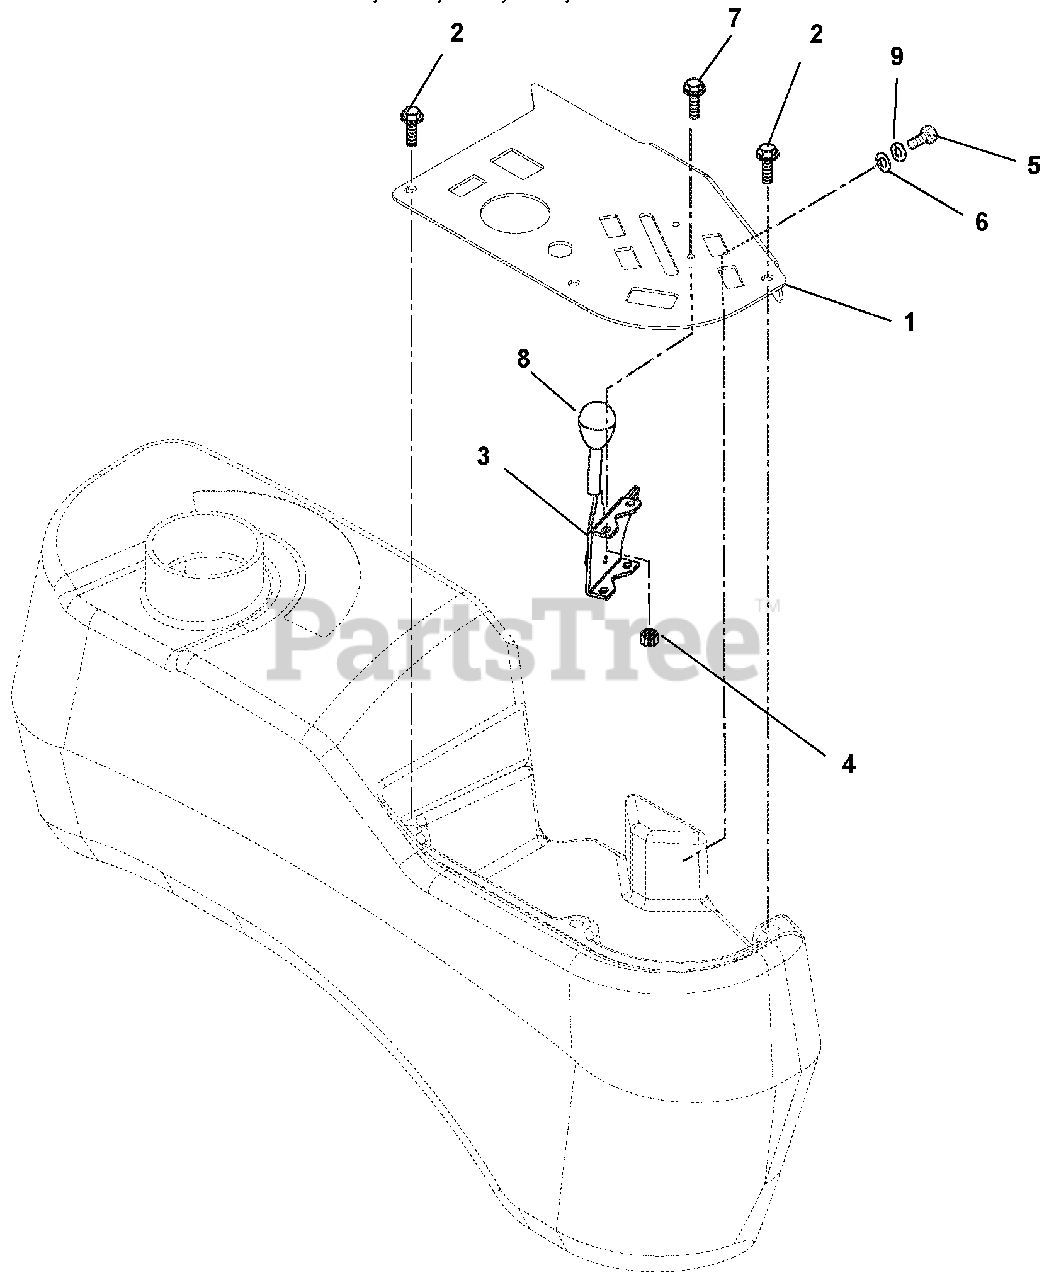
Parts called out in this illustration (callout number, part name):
1	Panel, Control, PM200 Diesel
2	Screw, Machine 10-24 x .38 Hex Washer Head Stainless
3	Throttle, Cable, 47.37"
4	Nut, Locking Nylon 10-24 with Insert
5	Bolt, Hex .31-18 x .75 Grade 5
6	Washer, Flat Steel .38 x .875 x .083
7	Screw, Machine 10-24 x .50 Hex Washer Head Stainless
8	Knob, Control, Black, .38-16 x .62
9	Washer, Locking .318 x .078
